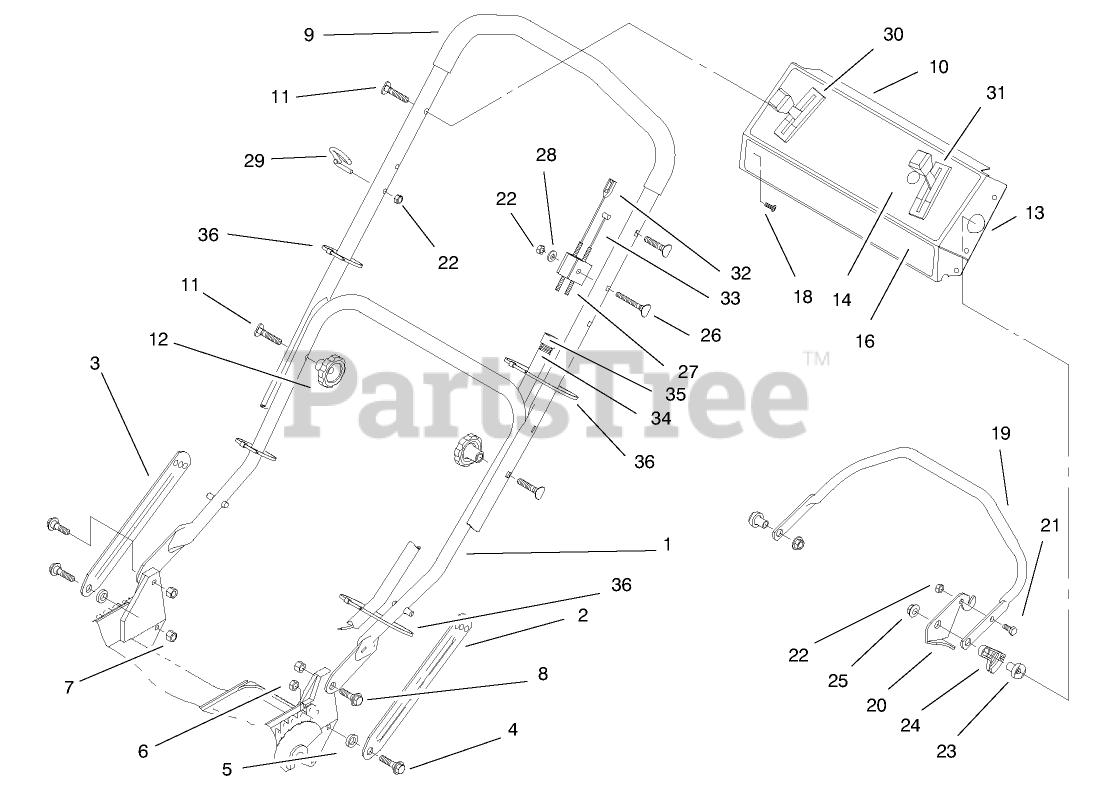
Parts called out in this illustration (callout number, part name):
4	SCREW-SHOULDER
5	SPACER
6	NUT-LOCK, NI
7	NUT-LOCK, NI
8	SCREW-SHOULDER
9	HANDLE - DIPPED
10	DECAL-PANEL, REAR
11	SCREW-HANDLE
13	ASM - PANEL W/DECALS
14	DECAL - INSTRUCTION
18	SCREW-TAP
21	SCREW-HH
22	NUT-LOCK, NI
23	SPACER-SUPPORT
24	LEVER-TRACTION
26	SCREW-HANDLE
27	SUPPORT-CABLE
28	WASHER-FLAT
29	GUIDE-ROPE
30	CONTROL-SPEED, GROUND
31	CABLE - THROTTLE
32	CABLE - BRAKE
33	CABLE-TRACTION
35	FITTING-RING
36	TIE-CABLE
